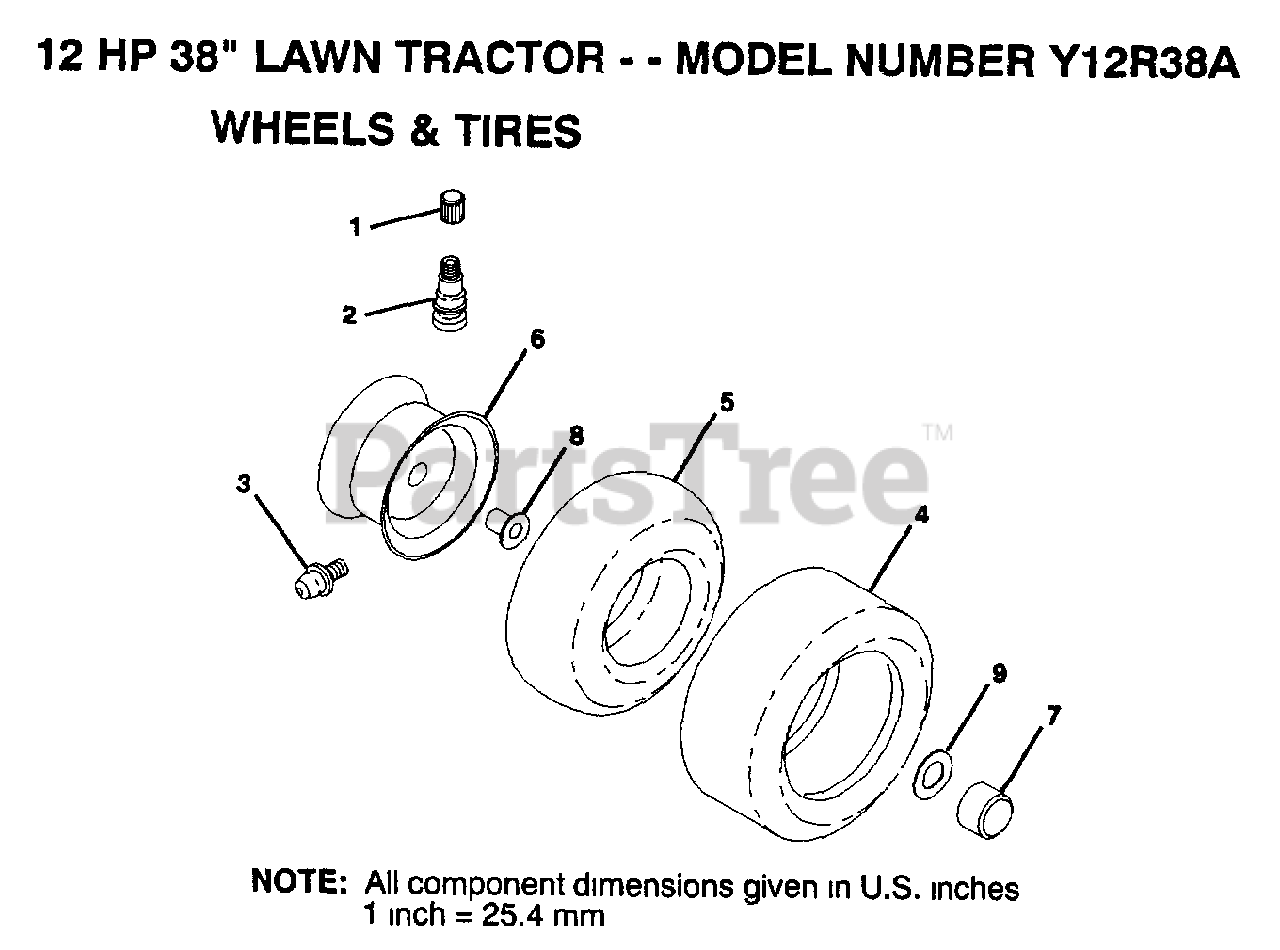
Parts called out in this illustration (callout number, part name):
1	VALVE CAP
2	VALVE STEM LT
3	FITTING LT
5	TUBE.5.3/4.5/6
7	HUB CAP
8	"FLANGE, BEARING"
9	WASHER
